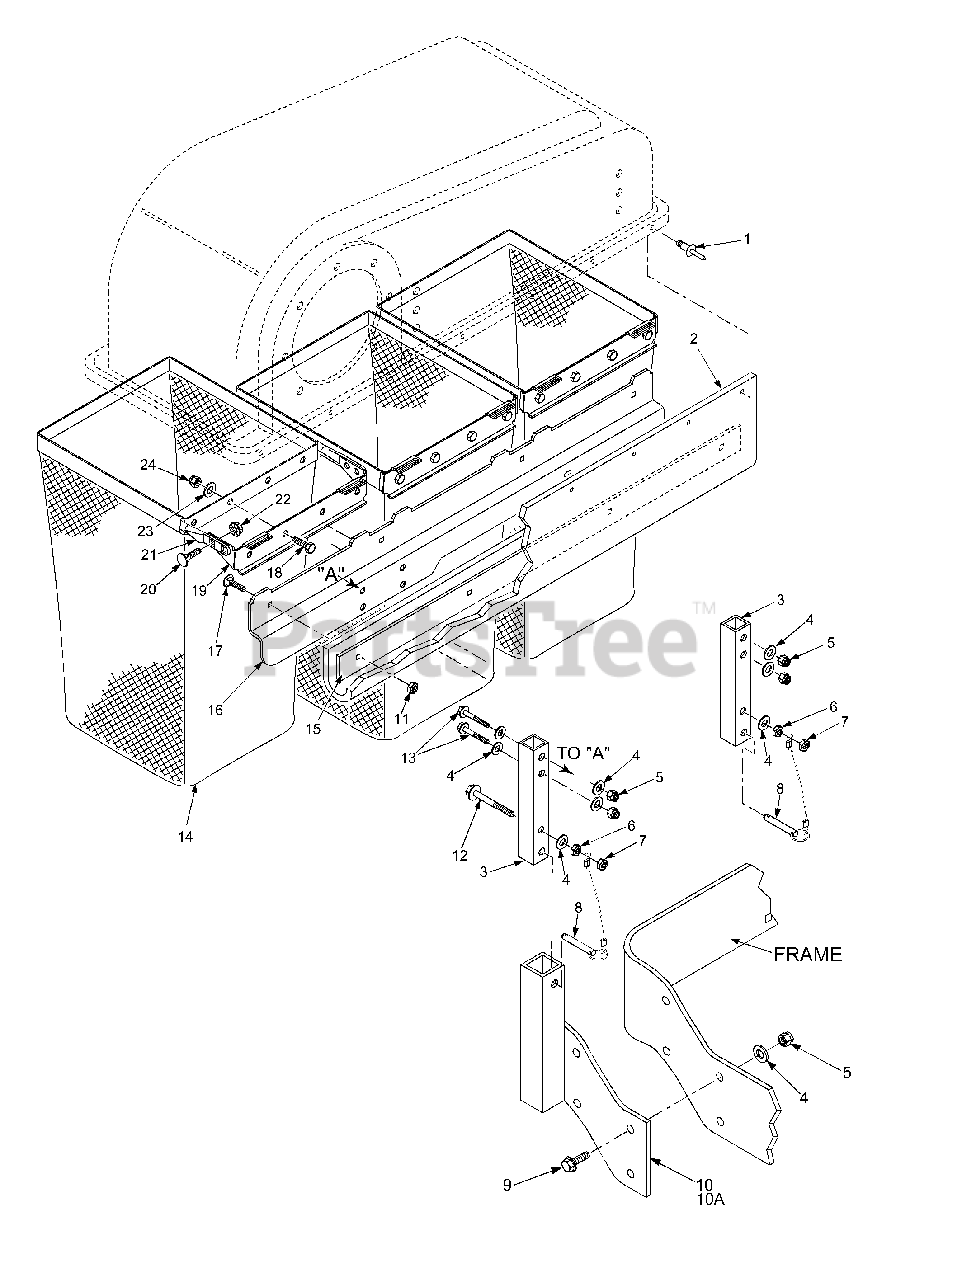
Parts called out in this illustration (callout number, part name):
1	Pop Rivet, 3/16 x .652
2	Seal, Hood
3	Tube, Upright
4	Flatwasher, 3/8-.391 x .938 x .105
5	Nut, Elastic Stop 3/8-16
6	Nut, 3/8-16
7	Hex Lock Nut, 3/8-16
8	Pin, Ring 1/2 x 2-1/4"
9	Bolt, Hex Head 3/8-16 x 1"
10	Mounting Bracket Weldment R.H.
10A	Mounting Bracket Weldment L.H.
11	Lock Nut, 1/4-20 Center
12	Bolt, Hex Head 3/8-16 x 2-1/4"
13	Bolt, Hex Head 3/8-16 x 2-1/2"
14	Bag Assembly, GC-STC
15	Retainer, Seal
16	Support, Bag Frame
17	Bolt, Carr. 1/4-20 x 3/4"
18	Bolt, Hex Head 5/16-18 x 3/4"
19	Mount, Bag Frame Tube
20	Bolt, Carr. 5/16-18 x 3/4"
21	Tube, Bag Support
22	Nut, Serr. Flange 5/16-18
23	Flatwasher, 5/16-.375 x .875 x .083
24	Nut, Elastic Stop 5/16-18
